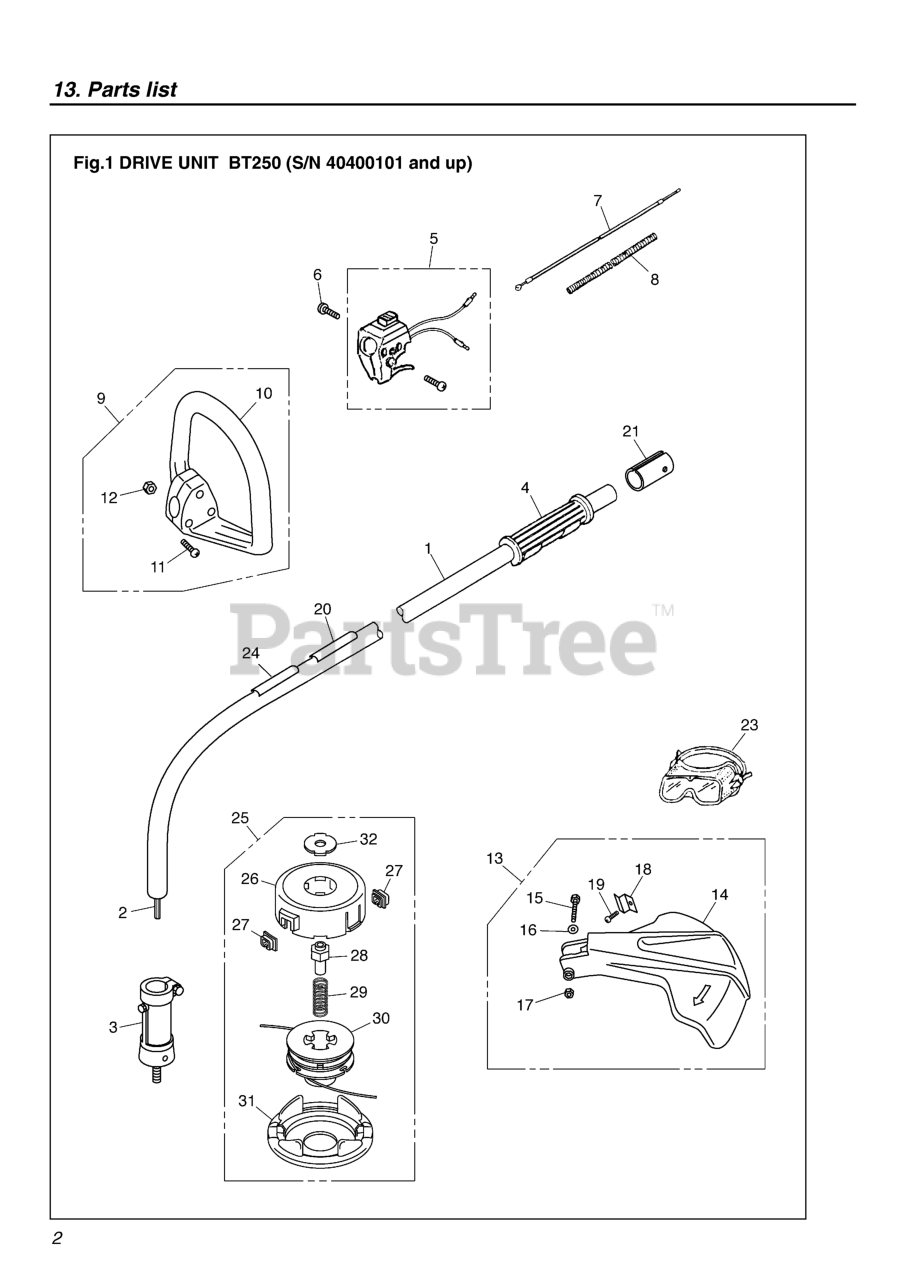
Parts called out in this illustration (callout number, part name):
1	PIPE COMP
2	DRIVE SHAFT (54
3	HOUSING ASSY.
5	LEVER ASSY.
7	CABLE COMP
9	HANDLE ASSY.
11	SCREW, M5 x 30
13	GUARD ASSY.
20	PLATE, NAME
23	GOGGLE
24	LABEL, CAUTION
25	TAP HEAD
27	EYELETK5300-0012
28	NUTK5300-001320-
30	CORD HOLDER (BOB
